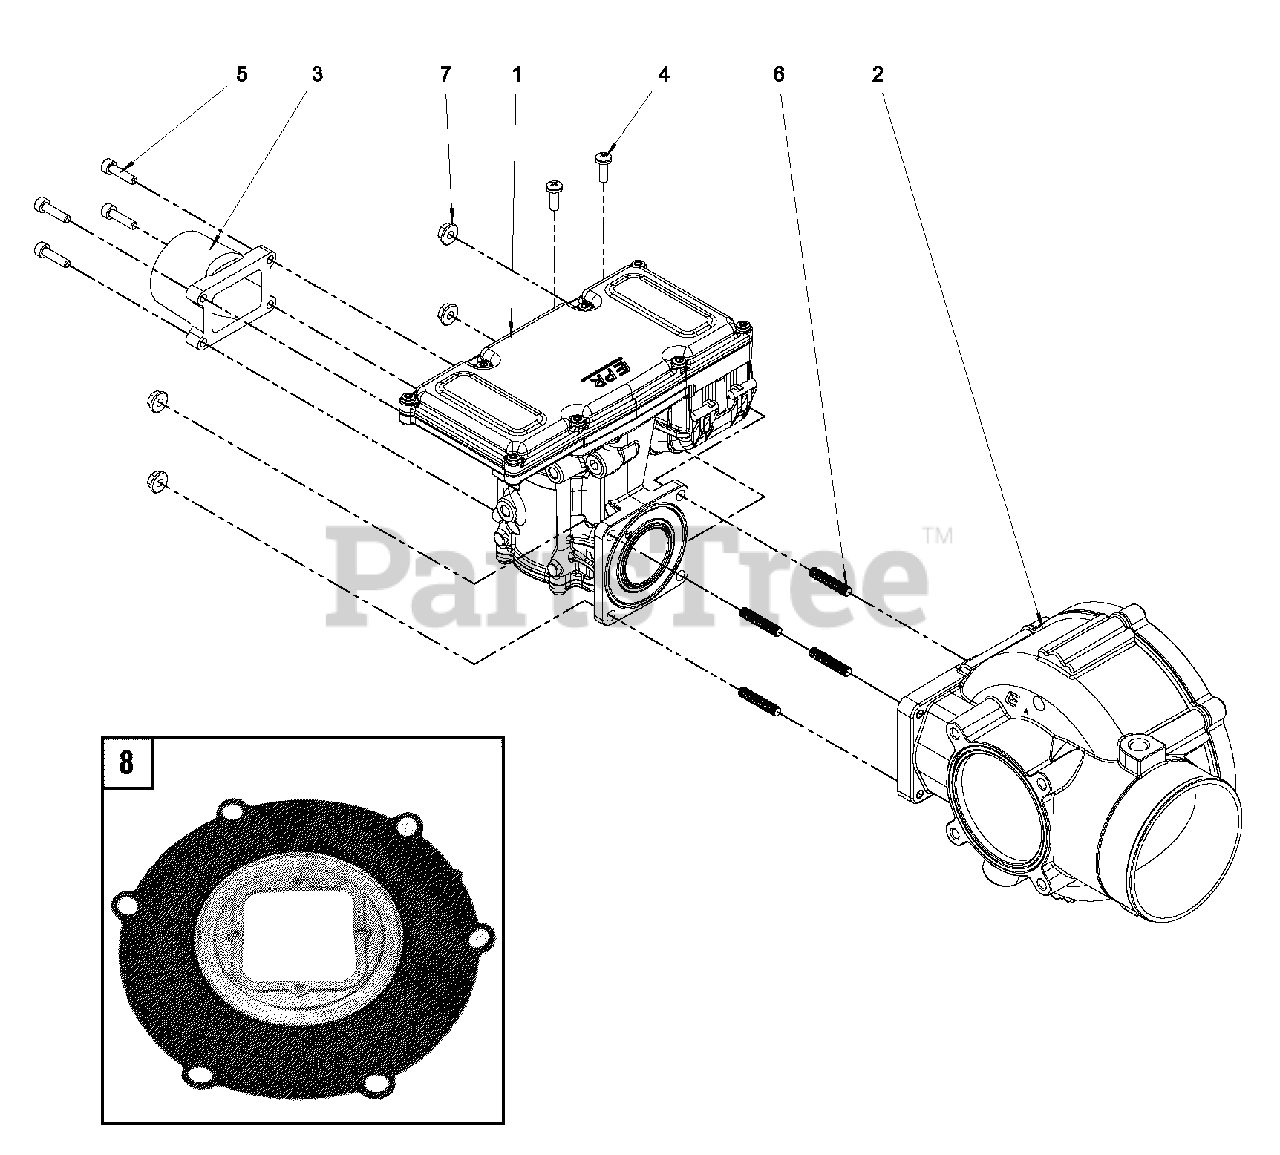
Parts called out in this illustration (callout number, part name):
1	PROGRAMMED EPR
3	* FITTING
4	* SCREW
5	* BOLT
6	* STUD
7	* NUT
8	MIXER REPAIR KIT
